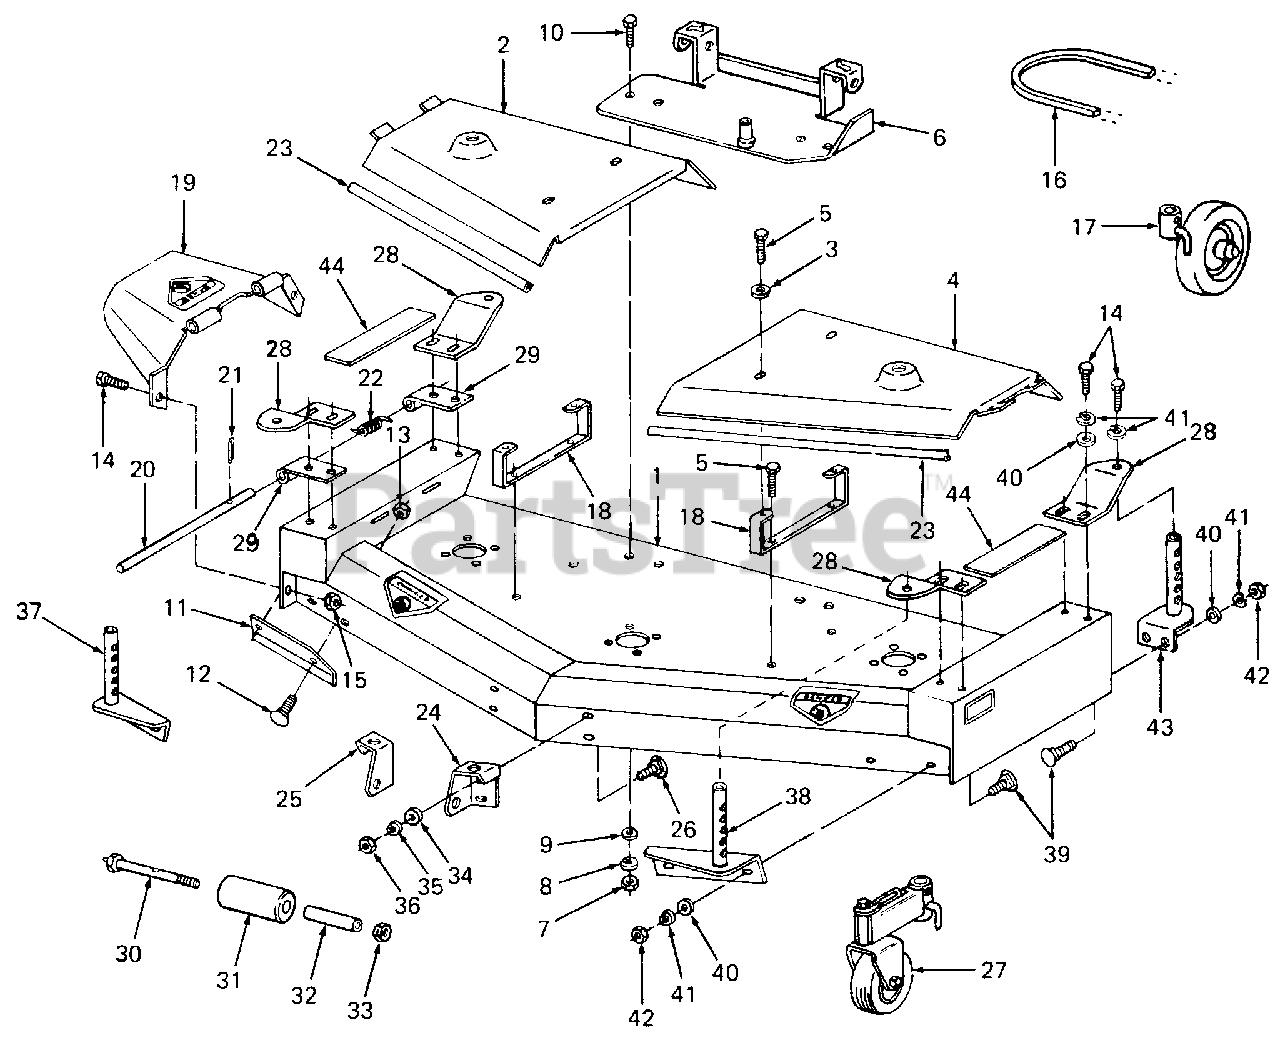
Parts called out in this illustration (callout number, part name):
1	Deck Assembly w/Graphics
2	Cover, Deck Belt RH
3	4 X.120 Thk Washer, Flat, .330 ID X 1.25 OD
4	Cover, Deck Belt LH
5	8 5/16-18 Screw, Hex Cap, Self Tapping
6	Plate, Idler
7	Nut, Hex, 1/2-13
8	Washer, Lock, 1/2
9	Washer, Flat, .510 X 1.00 X .060 Thk
10	Screw, Hex Cap, 1/2-13 X 1.25 Lg
11	Baffle, Discharge
12	Bolt, Carriage, 3/8-16 X .75 Lg
13	Nut, Hex Center Lock, 3/8-16
14	Bolt, Hex, 3/8-16 X 1.0 Lg GR5
15	Nut, Hex Flanged Lock, 3/8-16
16	Belt, Spindle Drive
17	Wheel, Complete Rear Gauge, 8"
18	Bracket, V-Belt Cover
20	Rod, Chute Deflector Mtg
21	Pin, Cotter, 1/8 Dia X 1.25 Lg
22	Spring, Deflector
23	Trim, Vinyl
24	Bracket, Front Roller Mtg LH
27	Wheel Assy, Complete Pivoting Gauge
28	Bracket, Wheel Support
29	Bracket, Deflector Hinge
30	Bolt w/Fitting
31	Roller, Front
33	Nut, Hex Center Lock, 1/2-13 GR5
34	Washer, 3/8 X 7/8 X .08
35	Washer, Lock, 5/16
36	Nut, Hex, 5/16-18 GR5
37	Bracket, Caster Mtg RH
38	Bracket, Caster Mtg LH
39	Bolt, Carriage, 3/8-16 X 1.0 Lg GR5
40	Washer, Flat, .438 X 1.0 X .064 Thk
41	Washer, Lock, 3/8
42	Nut, Hex, 3/8-16
43	Bracket, Gauge Wheel Mtg
44	Anti-Slip Abrasive Surface
